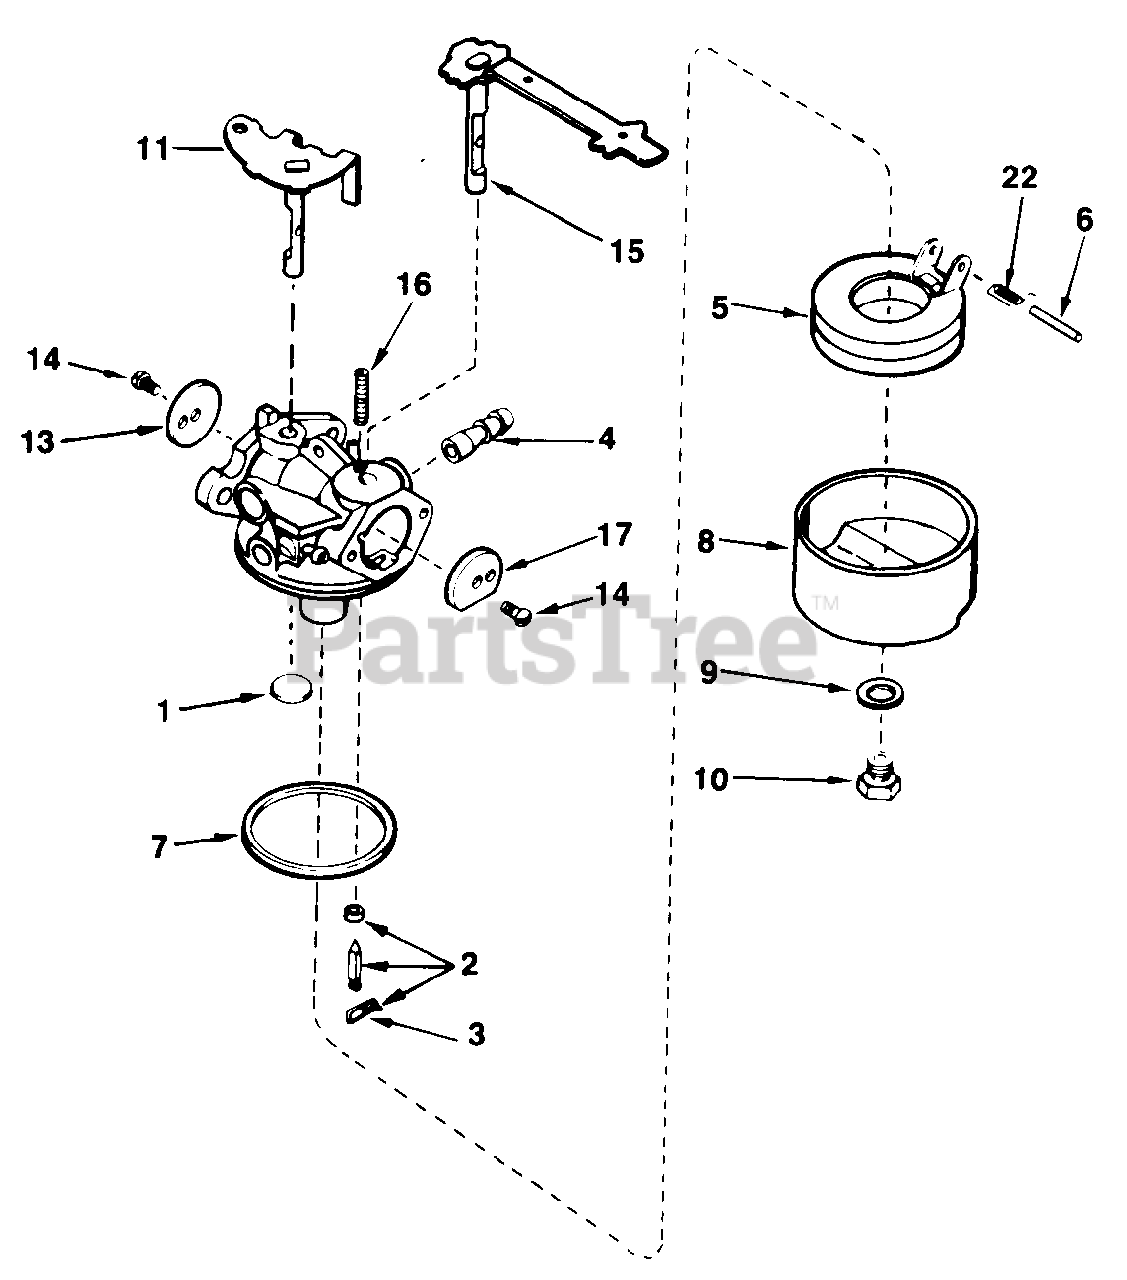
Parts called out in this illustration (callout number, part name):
1	Plug, Welch
2	Inlet Needle, Seat & Clip Ass'y.
3	Clip, Inlet Needle
4	Fitting, Fuel Inlet
5	Float, Carburetor
6	Shaft, Float
7	"O" Ring, Bowl-to-Body
8	Bowl, Float
9	Gasket, Bowl-to-Body
10	Nut, Float Bowl
11	Shaft & Lever Ass'y., Throttle
13	Shutter, Throttle
14	Screw, Throttle & Choke Shutter
15	Shaft & Lever Ass'y., Choke
16	Spring, Choke Positioning
17	Shutter, Choke
